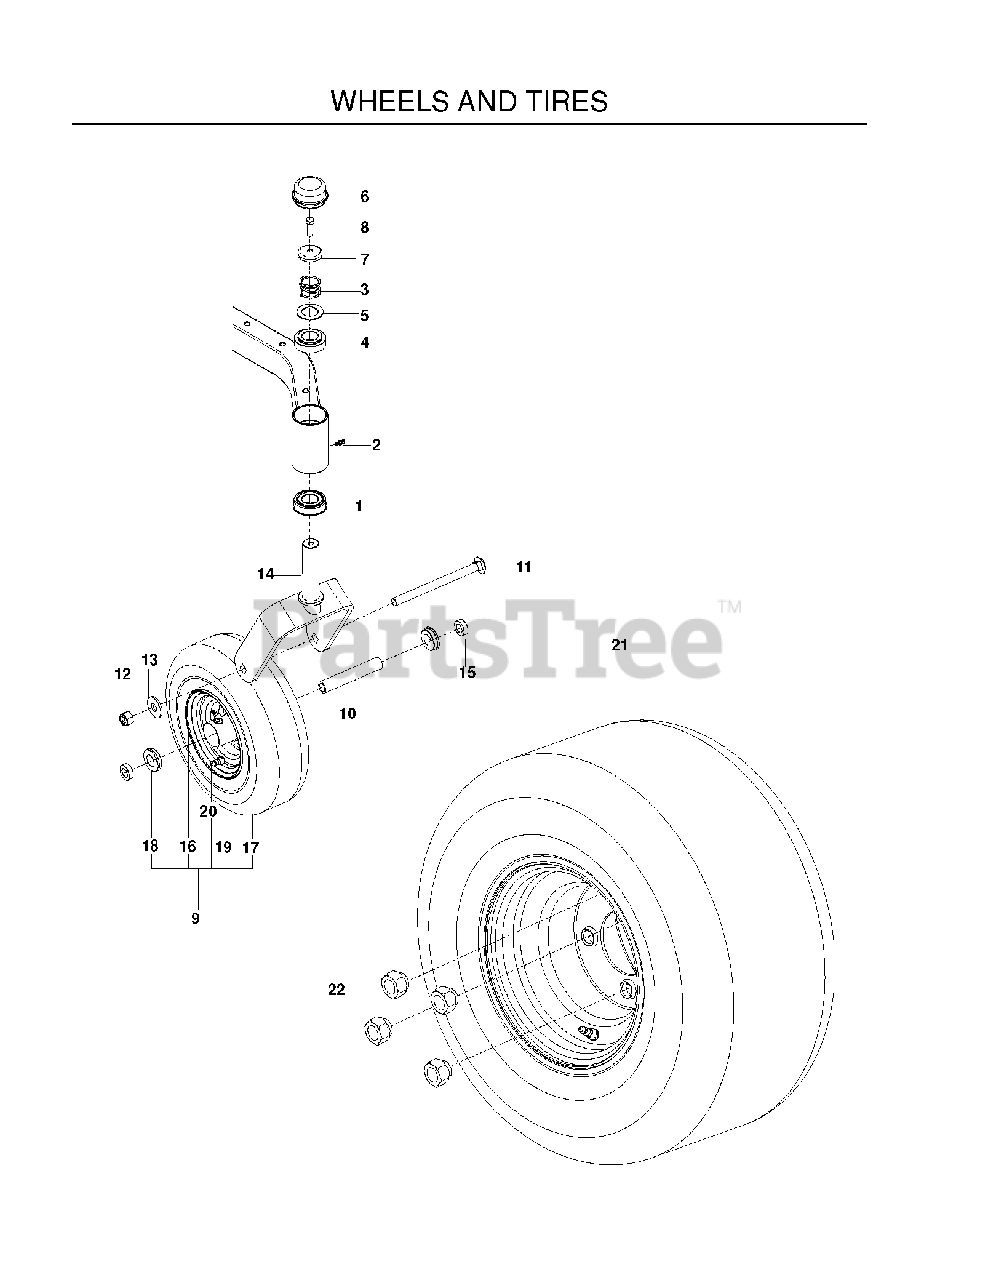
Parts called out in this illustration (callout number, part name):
1	BEARING FLANGED
2	ZERK, 3/16, DRIVE IN
3	SPRING, CASTER
4	BUSHING, CASTER
5	WASHER, 1.025 ID X 1.64
6	GREASE CAP
7	CASTER.PLUG
8	5/16-18X1 HHB G5W/NY
9	TIRE.ASSEM.CASTER.410-5.BLACK
11	RHSNB 1/2-13 X 6.50 GR2 ZD
12	NUT 1/2-13 HEX CNTRLK GR 5 ZD
13	WASH USS FLAT 1/2
14	YOKE, CASTER, YLW
15	SPACER, 5/16"
16	RIM, CASTER TIRE, BLK
17	TIRE.11"X4""-5.4PLY.SMOOTH.KEND
18	BUSHING, WHEEL, 3/4"
20	VALVE STEM TR-412
21	TIRE ASM, 18-8.5 BLK
22	LUG NUT 1/2F
